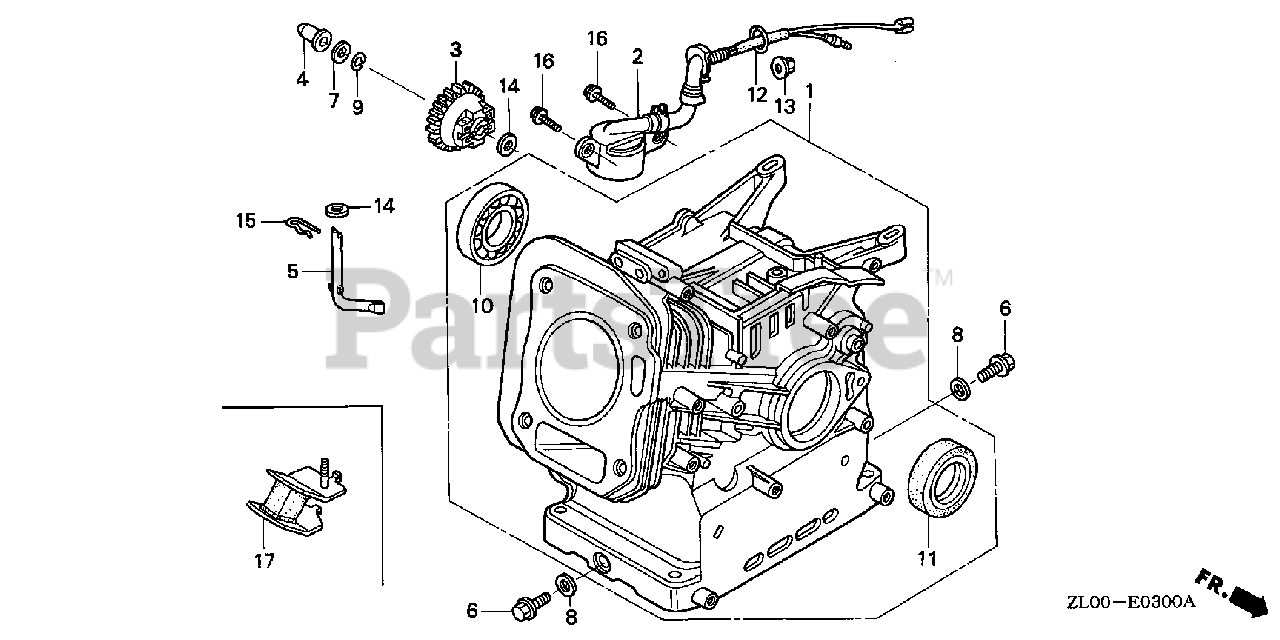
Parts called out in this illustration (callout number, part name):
1	CYLINDER ASSY.
2	SWITCH ASSY., OIL LEVEL
3	GOVERNOR ASSY.
4	SLIDER, GOVERNOR
5	SHAFT, GOVERNOR ARM
6	BOLT, DRAIN PLUG
7	WASHER, THRUST (6MM)
8	WASHER, DRAIN PLUG (10.2MM)
9	CLIP, GOVERNOR HOLDER
10	BEARING, RADIAL BALL (6205)
11	OIL SEAL (25X41X6)
12	O-RING (13.5X1.5) (ARAI)
13	NUT, FLANGE (10MM)
14	WASHER, PLAIN (6MM)
15	PIN, LOCK (8MM)
16	BOLT, FLANGE (6X12)
